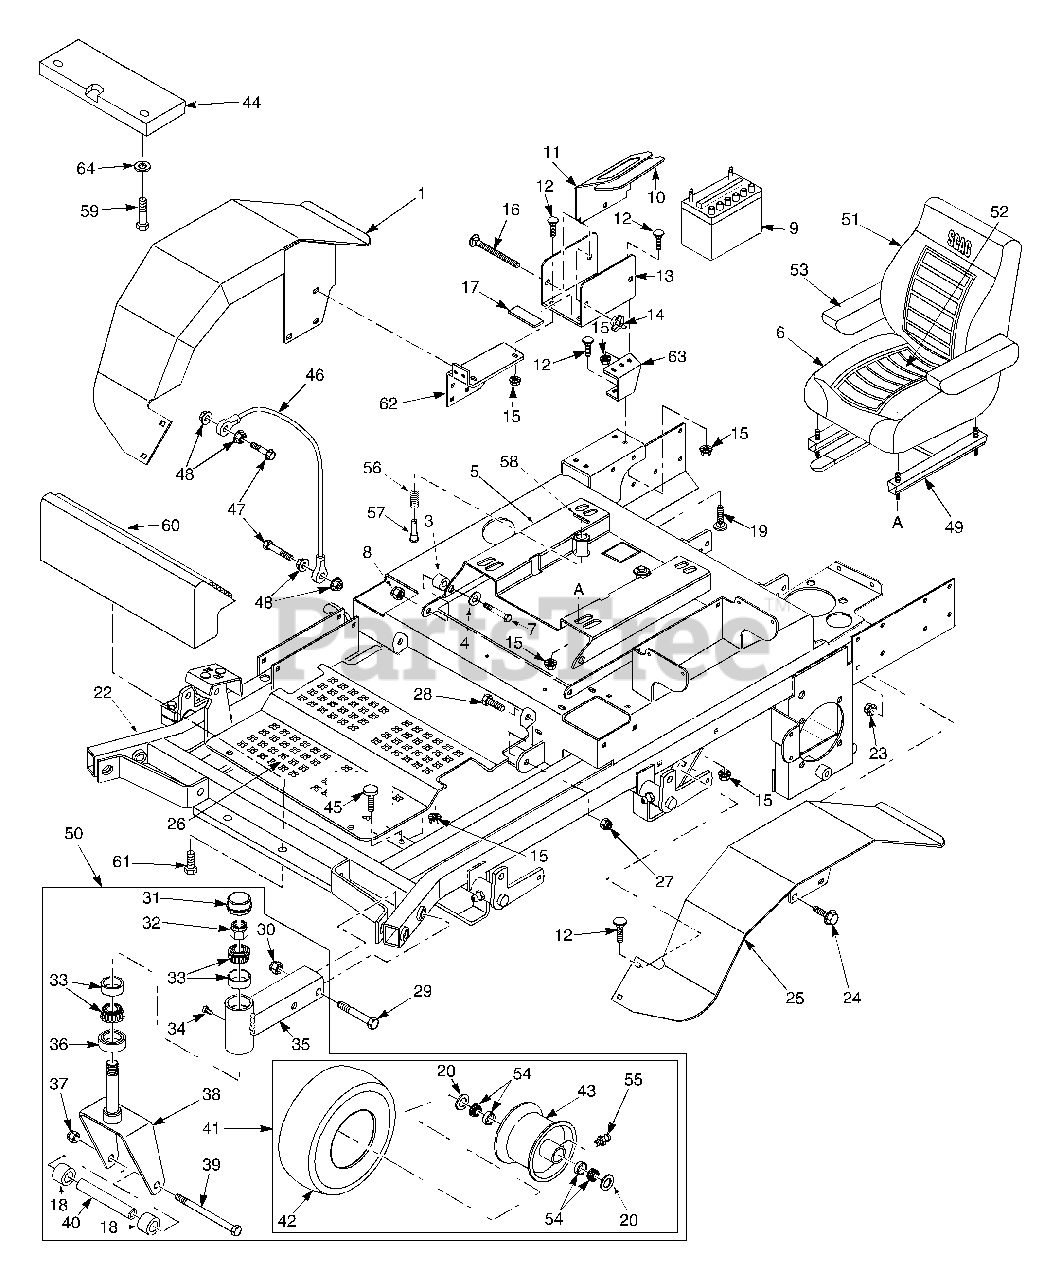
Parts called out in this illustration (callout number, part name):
1	Fender Weldment, RH
2	Bolt, Hex Head, 5/16-18 x 1, Zinc
3	Spacer
4	Flatwasher, 3/8-.391 x .938 x .105
5	Seat Plate Weldment
6	Seat Assembly w/armrest
7	Bolt, Hex Head 3/8-16 x 2.0"
8	Nut, Elastic Stop 3/8-16
9	Battery
10	Pad, Battery Cover
11	Cover, Battery
12	Bolt, Carriage 5/16-18 x 3/4"
13	Plate, Battery Box
14	Wing Nut, 1/4-20 x 3/4"
15	Nut, Hex Serrated Flange 5/16-18
16	Bolt, Carriage 1/4-20 x 6"
17	Rubber Pad
18	Spacer, Caster Wheel
19	Bolt, Carriage 5/16-18 x 1"
21	Lock Nut, 3/8-16, Elast. Stop
22	Main Frame
23	Nut, Hex Serrated Flange 3/8-16
24	Screw, Hex Serrated Flange 3/8-16 x 1"
25	Fender Weldment, LH
26	Foot Plate
27	Nut, Hex Elastic Stop 3/8-16
28	Bolt, Hex Head 3/8-16 x 1"
29	Bolt, Hex Head 5/8-11 x 4"
30	Nut, Hex Elastic Stop 5/8-11
31	Cap, Grease
32	Nut, Hex Elastic Stop 1.0-14
33	Bearing W/Race
34	Plug, 1/4-28 THD Form
35	Extention Weldment, Caster 61A (LH)
36	Seal, 2.00 OD. x 1.625 Bore
37	Nut, Hex Elastic Stop 1/2-13
38	Yoke Weldment, Caster (61A & 72A)
39	Bolt, Hex Head 1/2-13 x 9-1/2" (61A & 72A)
40	Sleeve, Caster Wheel (61A, 72A)
41	Wheel Assy(Inc.items 20, 42, 43, 54, 55)
42	Tire, 13 x 6.50 4-Ply (61A, 72A)
43	Rim Assembly, 61A & 72A (Inc. item 55)
44	Weight (61" cutter deck only)
45	Bumper, Rubber
46	Cable, Seat Stop
47	Bolt, Hex Head 1/4-20 x 1-1/4"
48	Nut, Hex Serrated Flange 1/4-20
49	Seat Adjustment, Track Set
50	Caster Wheel Assy 61A (LH)
51	Back Cushion Cover
52	Seat Cushion Cover
53	Arm Rest, Right Hand
54	Bearing w/ Race
55	Grease Fitting
56	Spring, Seat
57	Pin Retainer, Spring
58	Roll Pin, Spring 5/32 x 3/4"
59	Bolt, Hex Head 1/2-13 x 3.5"
60	Footrest
61	Bolt, Hex Head 1/2-13 x 1.5"
62	Mounting Bracket, Battery
63	Support Bracket, Battery Box
64	Flat Washer 1/2-.562 x .1.375 x .109
